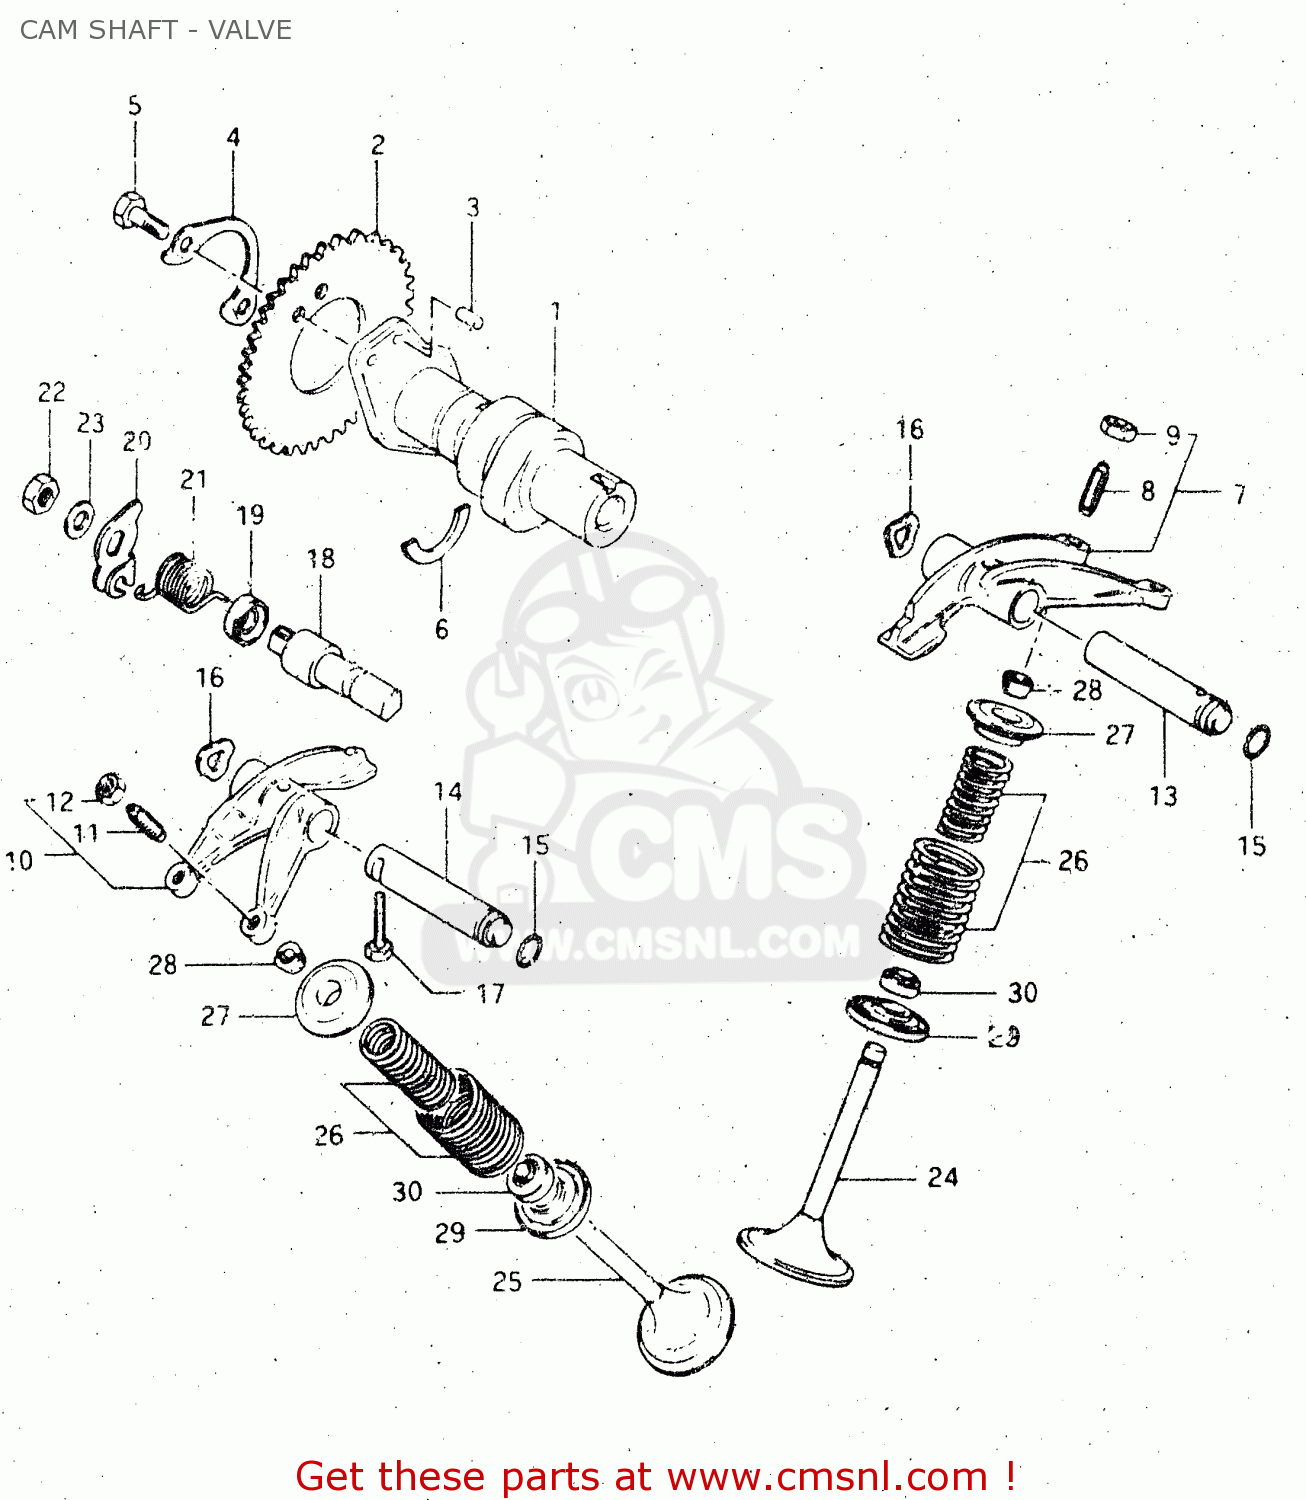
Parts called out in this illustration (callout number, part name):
1	CAMSHAFT
2	SPROCKET,CAMSHAFT(NT:42)
3	PIN
4	WASHER,CAM CHAIN SPROCKET
5	BOLT(6X12.5)
6	C RING
7	ARM,VALVE ROCKER
8	SCREW,TAPPET ADJUSTING
9	NUT,ADJUSTING SCREW
10	ARM,VALVE ROCKER,EXHAUST
11	SCREW,TAPPET ADJUSTING
12	NUT,ADJUSTING SCREW
13	SHAFT,VALVE ROCKER,INTAKE
14	SHAFT,VALVE ROCKER,EXHAUST
15	O RING(D:1.9,ID:8.6)
16	WASHER
17	BOLT(6X23)
18	SHAFT,DECOMPRESSION
19	OIL SEAL
20	LEVER,DECOMPRESSION SHAFT
21	SPRING
22	NUT 8MM
23	WASHER,8.5X16X
24	VALVE,INTAKE
25	VALVE,EXHAUST
26	SPRING SET,VALVE
27	RETAINER,VALVE SPRING
28	COTTER VALVE
29	SEAT,VALVE SPRING
30	SEAL,OIL(7X14.4X9)
